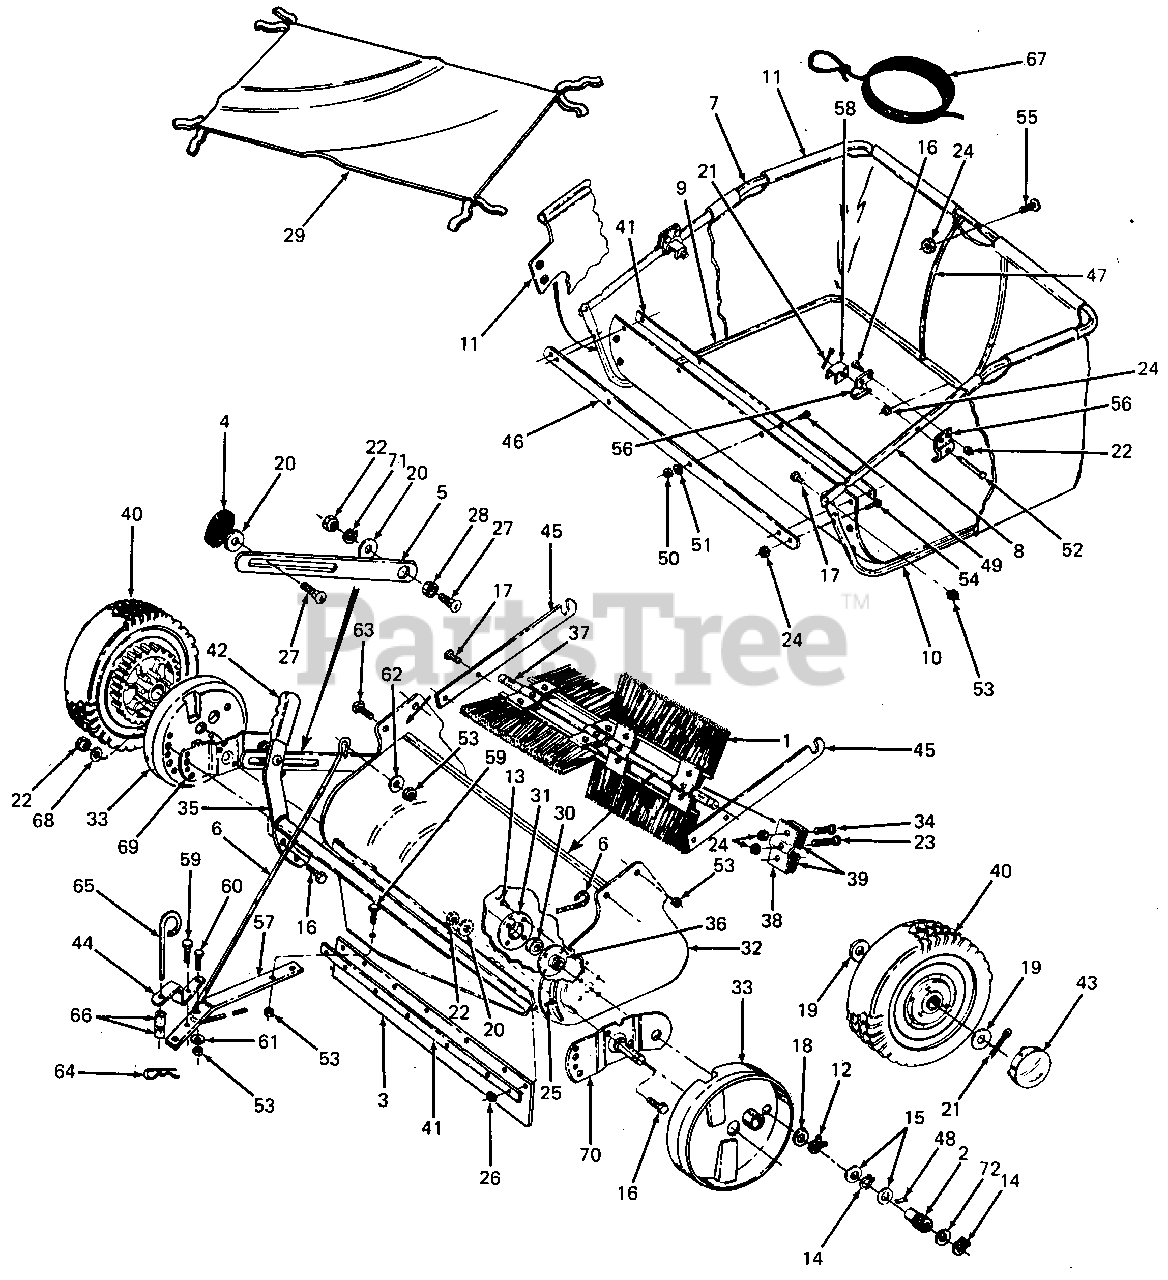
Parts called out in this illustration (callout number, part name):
2	Gear, Pinion LH
4	Knob, Height Adjustment
5	Strap, Height Adjustment
6	Rod, Brace
7	Tube, Upper Hopper RH
8	Tube, Upper Hopper LH
9	Tube, Lower Hopper RH
10	Tube, Lower Hopper LH
11	Bag, Hopper
12	Ring, Retaining, 3/4"
14	Ring, Retaining
15	Washer, Flat, .596 X 1.125 X .025
16	Screw, Hex Cap, 5/16-18 X .75 Lg GR 5
17	Screw, Hex Cap, 3/8-16 X .75 Lg GR 5
18	Washer, .783 X 1.125 X .025
19	Washer, .51 X 1.0 X .02
20	Washer, .344 X .62 X .063
21	Pin, Cotter, 1/8 X 3/4 Lg
22	Nut, Hex Center Lock, 5/16-18
23	Screw, Hex Cap, 1/4-20 X 1.0 Lg
24	Nut, Hex Patch Lock, 1/4-20
25	Screw, Truss Mach., #10-24 X .50 Lg
26	Nut, Hex, #10-24
27	Bolt, Carriage, 5/16-18 X .75 Lg
28	Spacer, Bushing
29	Screen, Wind
30	Bearing, Ball
31	Retainer, Bearing
32	Housing Assy, Sweeper
33	Cover, Dust
34	Screw, Hex Cap, 1/4-20 X .75 Lg GR 5
35	Tube Assy, Height Adjustment
36	Bushing Assy, Brush
37	Shaft, Brush
38	Retainer, Brush (Double)
39	Retainer, Brush (Single)
40	Wheel Assy, Complete
41	Retainer, Skirt
43	Hub Cap
45	Arm, Bag Mount
46	Strap, Bag Frame
47	Support, Wire
48	Pawl (H.T.)
49	Screw, Truss Hd, Slotted, #10-32 X .62 Lg
50	Nut, Hex Mach., #10-32
51	Washer, Lock, #10
52	Pin, Clevis, 3/8 Dia X 3" Lg
53	Nut, Hex Center Lock, 3/8-16
54	Screw, Hex Cap, 1/4-20 X 1.25 Lg
55	Bolt, Curved Head, 1/4-20 X 1.0 Lg
56	Clamp, Hopper Mount
57	Bar, Hitch
58	Clevis, Bag Retainer
59	Screw, Hex Cap, 3/8-16 X 1.0 Lg GR 5
60	Screw, Hex Cap, 3/8-16 X 1.5 Lg GR 5
61	Washer, Flat, .510 X 1.5 X .08
62	Washer, Flat, .406 X 1.25 X .100
63	Screw, Hex Cap, 3/8-16 X 1.25 Lg GR 5
64	Hairpin Cotter
65	Pin, Hitch
66	Tube, Hitch Adjustment
67	Rope, Hopper
68	Washer, Flat, .34 X .68 X .062
69	Hanger Assy, Wheel RH
70	Hanger Assy, Wheel LH
71	Washer, Lock, 5/16
72	Washer, .596 X .859 X .025
